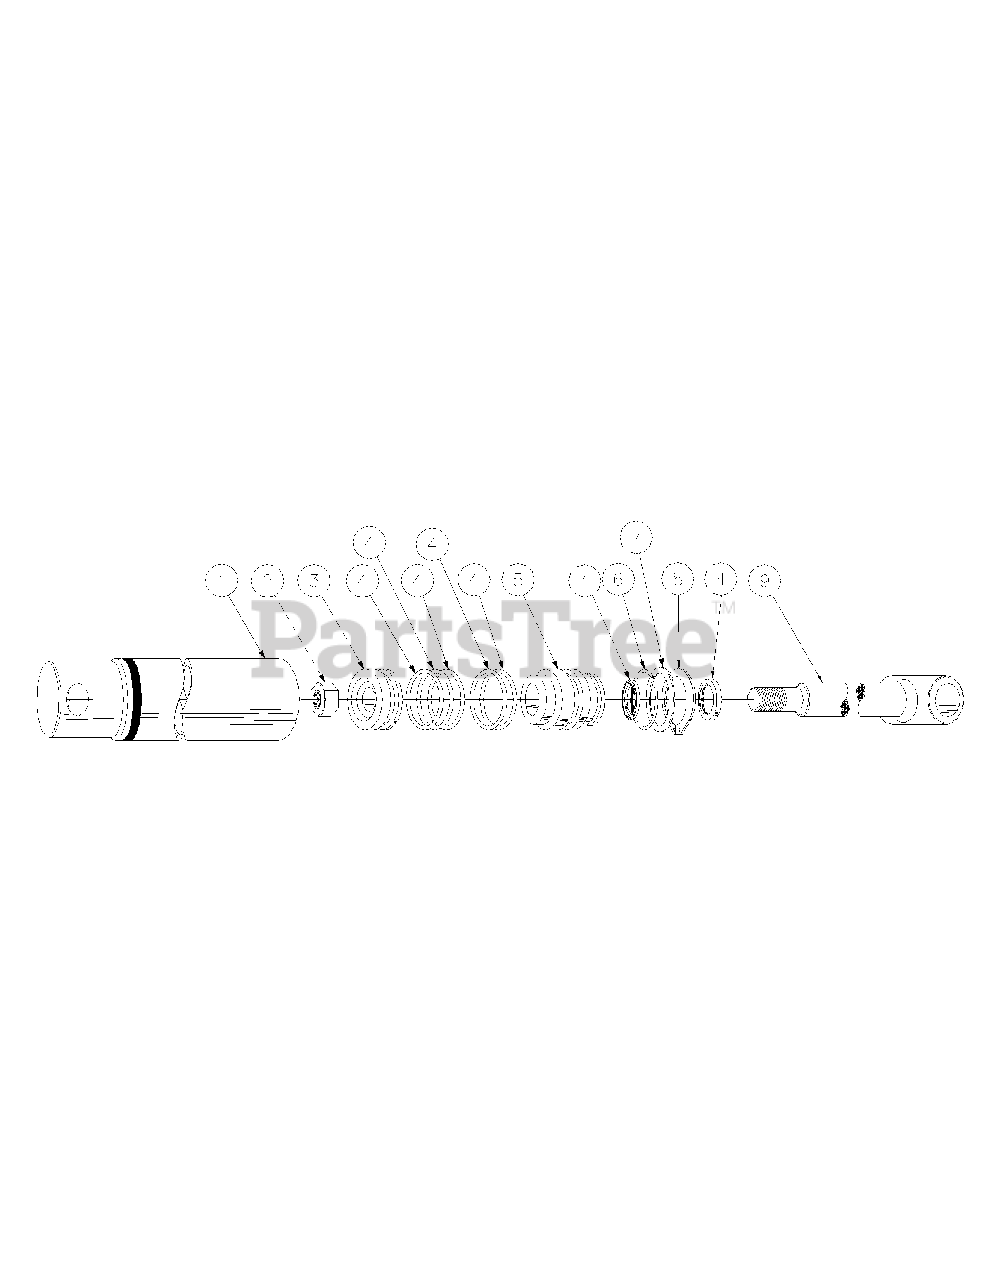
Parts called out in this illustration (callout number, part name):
1	Tube Assembly
6	Retaining Ring
8	Retaining Ring
9	Rod Assembly - LH
9	Rod Assembly - RH
